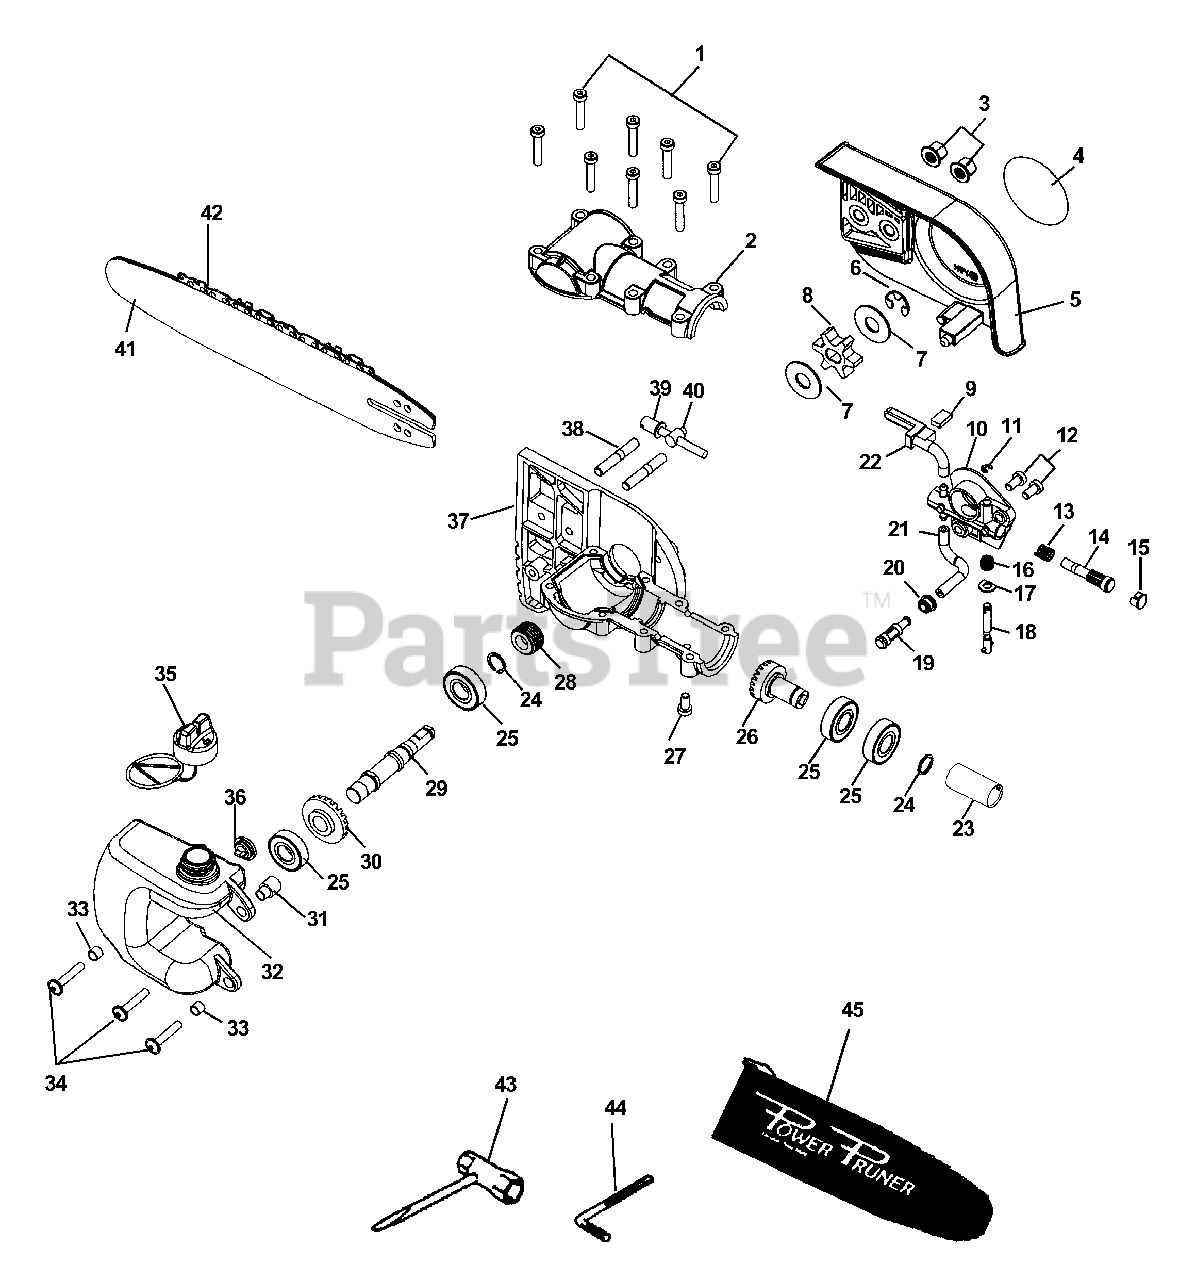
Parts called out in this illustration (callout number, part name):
1	SCREW M5×.25
2	COVER, GEAR CASE
3	NUT, FLANGE M6
4	LABEL, ECHO
5	GUARD, SPROCKET
6	RING, RETAINING Ø0.300
7	WASHER 10.2×24.5×1.2
8	SPROCKET, DRIVE
9	PAD, FOAM
10	AUTO-OILER ASSY
12	SCREW M5×.8×10
14	PLUNGER ASSY
15	CAP, OIL PUMP
18	ADJUSTER, OILER
19	FILTER, OIL
20	GROMMET
21	PIPE, IMPULSE 3×6×75
22	PIPE, OIL OUTLET
23	COLLAR - 22
24	RING, SNAP Ø12
25	BEARING, BALL
26	GEAR, BEVEL
27	SCREW M5×.8×10
28	GEAR, WORM
29	SHAFT, GEAR
30	GEAR, BEVEL
31	COLLAR 6
32	TANK, OIL
33	SPACER 6.2×7.8×6
34	SCREW 5×28
35	CAP ASSY, OIL
36	VENT ASSY
37	CASE, GEAR - LOWER
38	BOLT, STUD 6
40	TENSIONER, CHAIN
41	GUIDE BAR - 10"
41	GUIDE BAR - 10" -- INTENZ
42	SAWING CHAIN - 91VG -- 10"
43	T-WRENCH 10×19 MM
44	WRENCH, ALLEN 3 MM
45	COVER, GUIDE BAR
